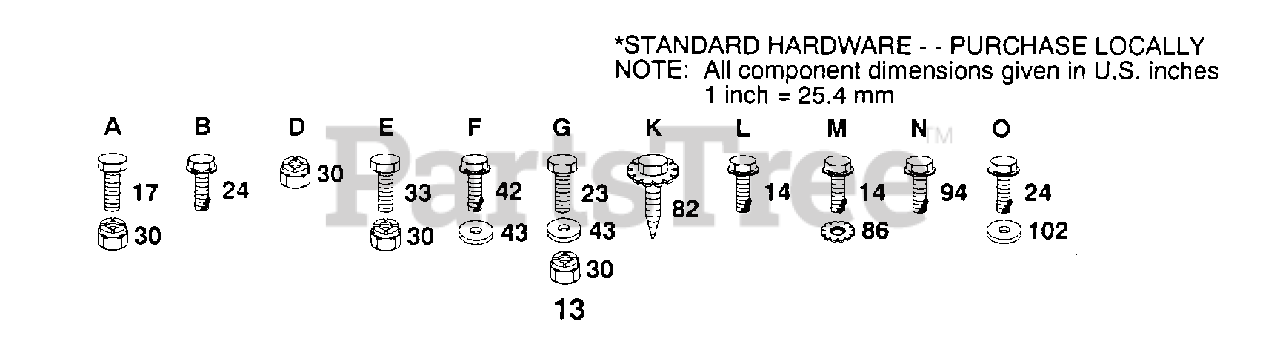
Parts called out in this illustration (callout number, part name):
13	BRACKET MUFFLER
14	SCREW LT
17	BOLT
23	BOLT
24	SCREW
42	SCREW
43	WASHER
86	LOCKWASHER
102	WASHER
